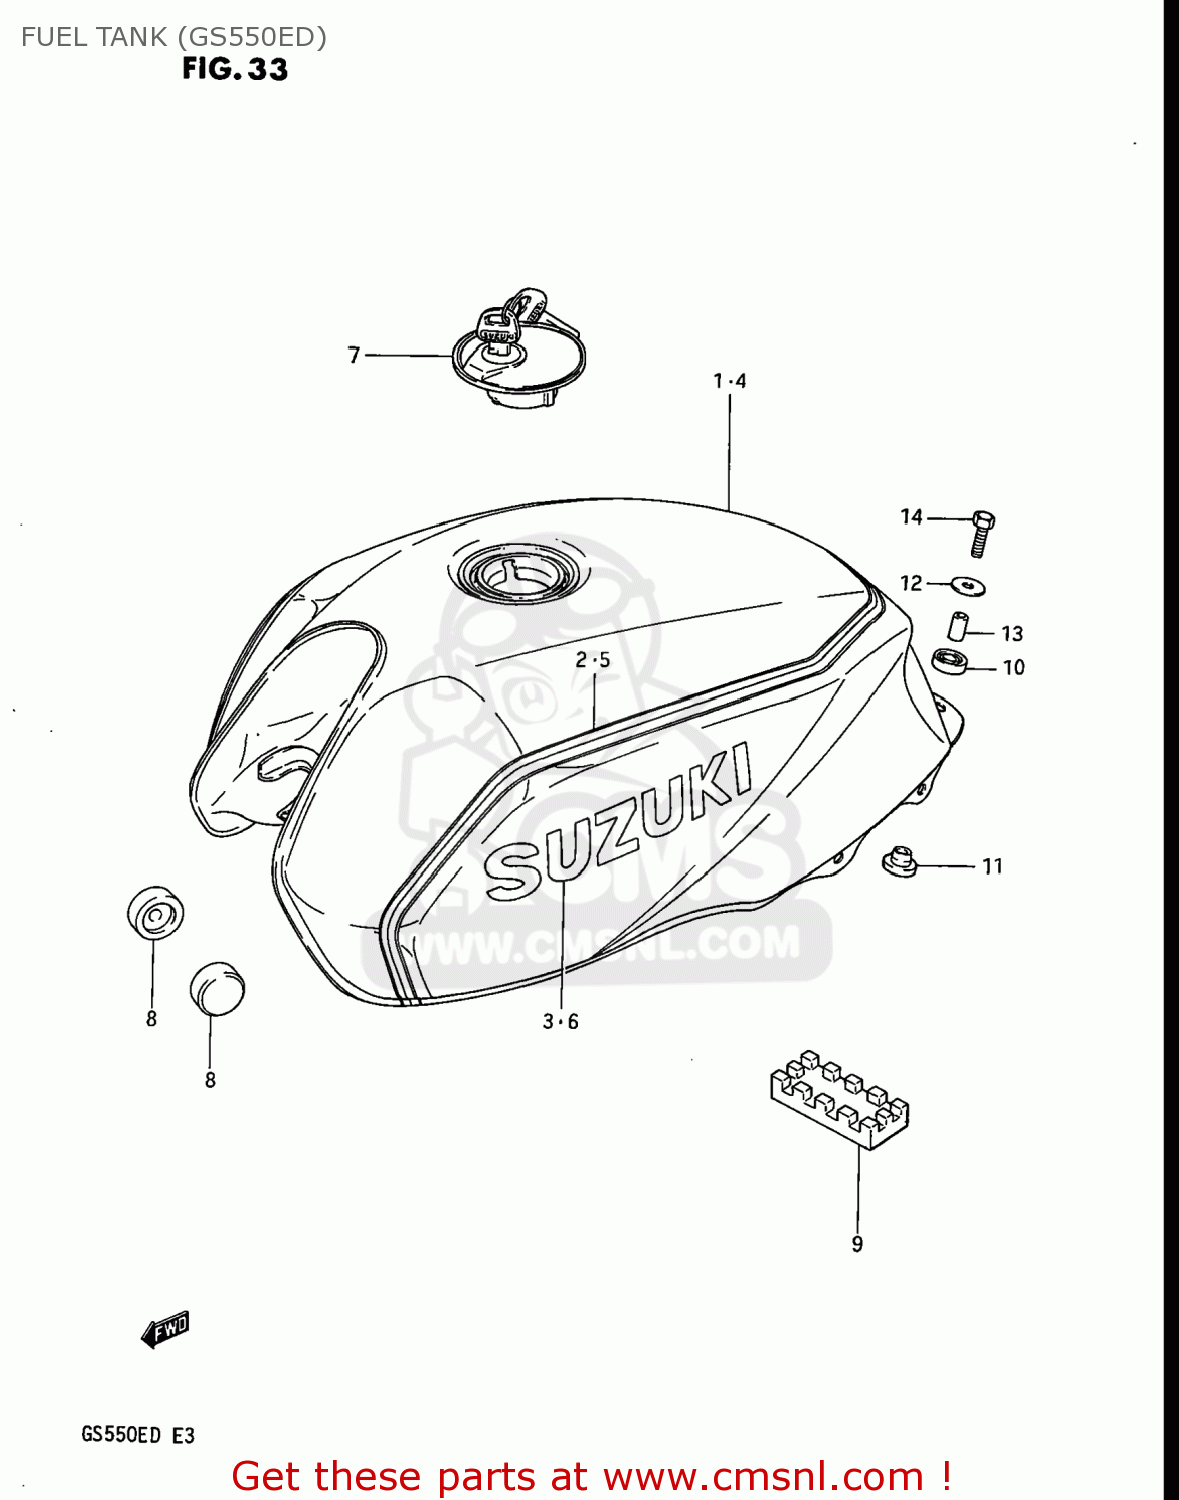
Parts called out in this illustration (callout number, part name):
1	TANK ASSEMBLY,FUEL
2	TAPE SET,FUEL TANK
3	EMBLEM
4	TANK ASSEMBLY,FUEL
5	TAPE SET,FUEL TANK
6	EMBLEM
7	CAP SET,FUEL TANK
8	CUSHION
9	CUSHION,FUEL TANK
10	CUSHION
11	CUSHION
12	WASHER (6.5X24X1.6)
13	SPACER
14	BOLT
